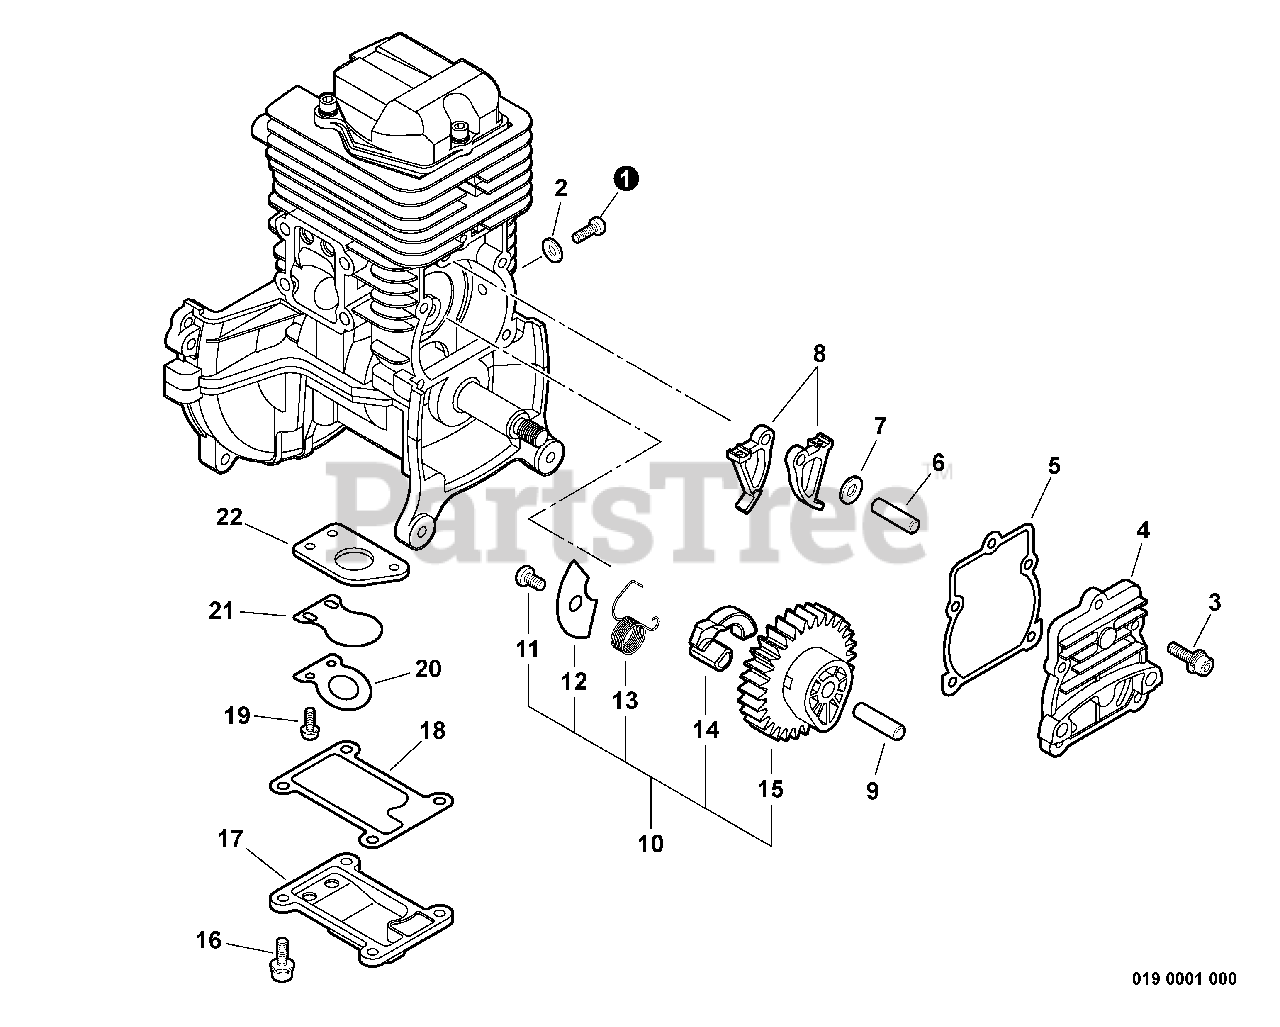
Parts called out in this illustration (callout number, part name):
1	SCREW - 5
2	WASHER - 10
3	SCREW - 4X14
4	COVER, CAM GEAR
7	WASHER - 5
8	FOLLOWER, CAM
10	CAM GEAR ASSY
11	SCREW - 4X6 -- TAPPING
12	PLATE, COVER
15	GEAR, CAM
16	SCREW - 4X12
17	COVER, REED VALVE
18	GASKET, REED VALVE
19	SCREW - 3X10
20	STOP, REED VALVE
21	VALVE, REED
22	PLATE, REED BACKING
